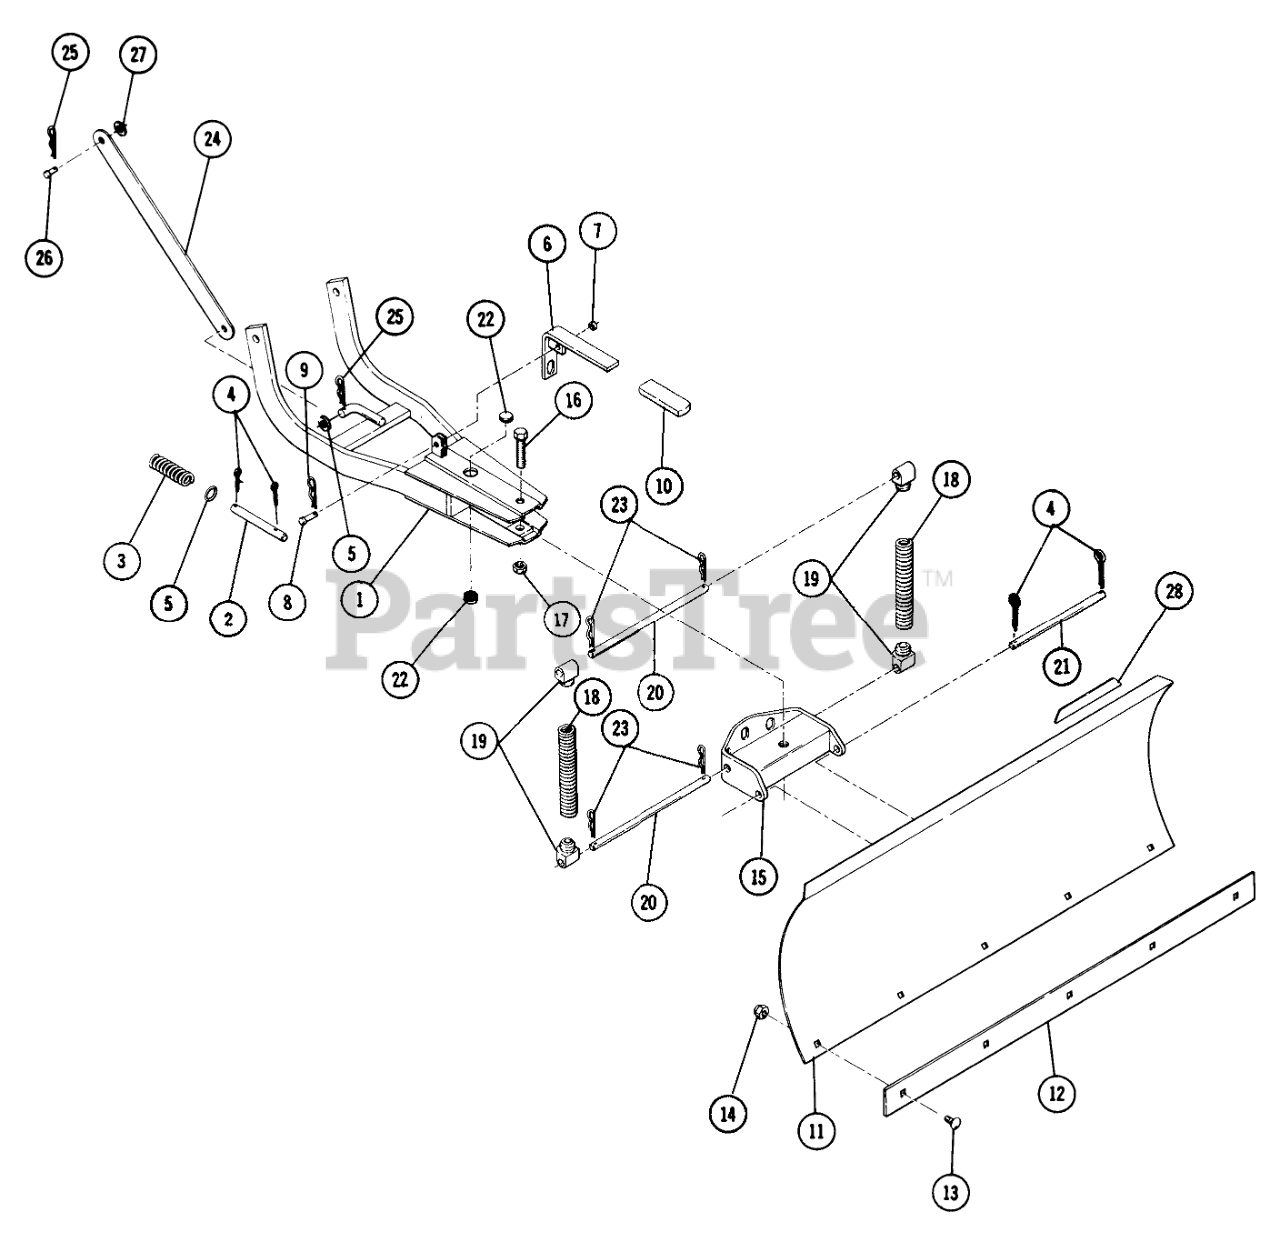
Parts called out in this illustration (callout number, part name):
1	Frame
2	Index Pin
3	SPRING-COMPRESSION
4	Cotter Pin
5	Washer, 5/8
6	Lever-Indexing
7	Washer
9	Hairpin
10	GRIP
11	Blade
12	Plate
13	Bolt-3/8-16 x 3/4
14	Nut 5/16-18
15	Sector and Channel
16	Bolt Hex 3/4-16 x 3 3/4
17	Nut-3/4-16 E.S.
18	Spring
19	Lug
20	ROD-PIVOT, BLADE
21	Tape-Insulator
22	PLUG
23	Hairpin
24	Bar-Lift
25	Hairpin-Upper
27	Washer
28	Decal
